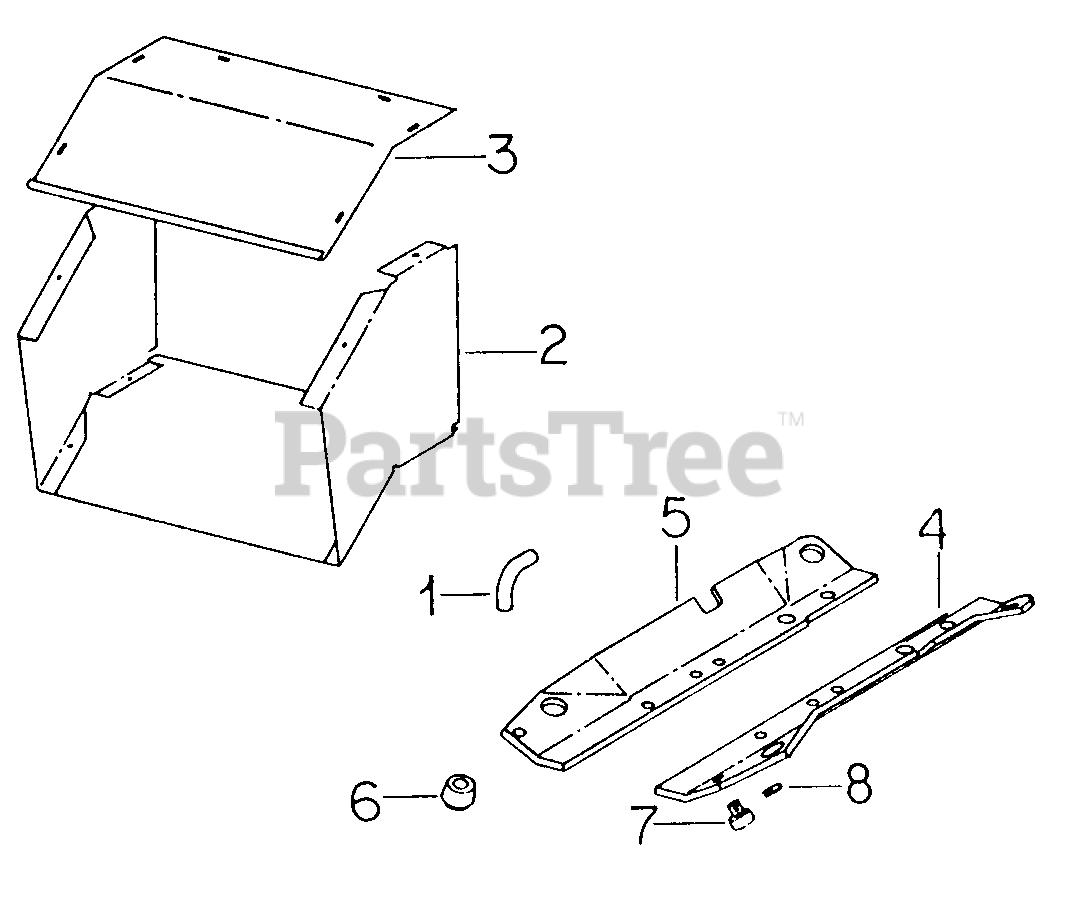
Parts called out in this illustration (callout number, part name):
1	Pipe, Oil Drain
1	Plug, 1/4-18 Automotive Hex Hd Pipe
2	Duct Assy, Air
2	Screw, 1/4-20 X 1/2 Hex Hd Flange Lock
3	Top, Air Duct
3	Screw, No. 10-32 X 3/8 Znd Hd Flange Lock
4	Frame, Engine Mount LH
5	Frame, Engine Mount RH
6	Mounting Kit, Engine
6	Bolt, 3/8 X 2-1/4 Type 5
6	Nut, 3/8 Cad P/T Lock Type 5
7	Bumper, Snubbing Mount
8	Shim, Snubbing Mount
8	Nut, 1/4 Type 5
